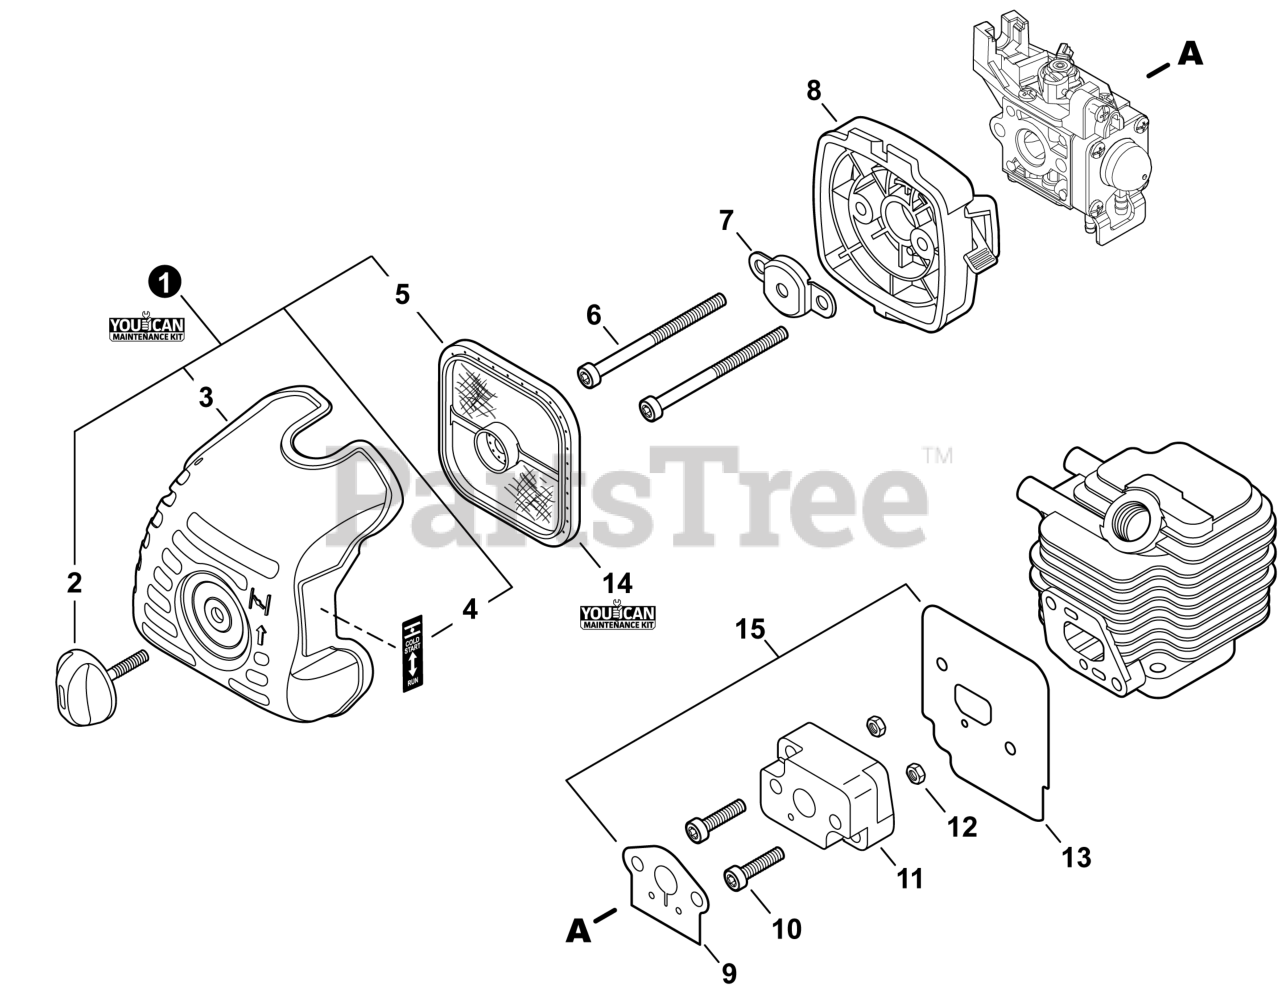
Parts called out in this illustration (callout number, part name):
1	FILTER KIT, AIR - YOUCANT
2	THUMBSCREW
3	COVER, AIR FILTER
4	LABEL - CHOKE
5	FILTER, AIR - DOUBLE LAYER
6	BOLT, TORX 5×65
7	PLATE, PREVENT
8	CASE ASSY, AIR FILTER
9	GASKET, INTAKE
10	BOLT, TORX 5×20
11	INSULATOR, INTAKE
13	HEAT SHIELD, INTAKE
14	TUNE-UP KIT - YOUCANT
15	GASKET KIT: ENGINE, INTAKE, EXHAUST
